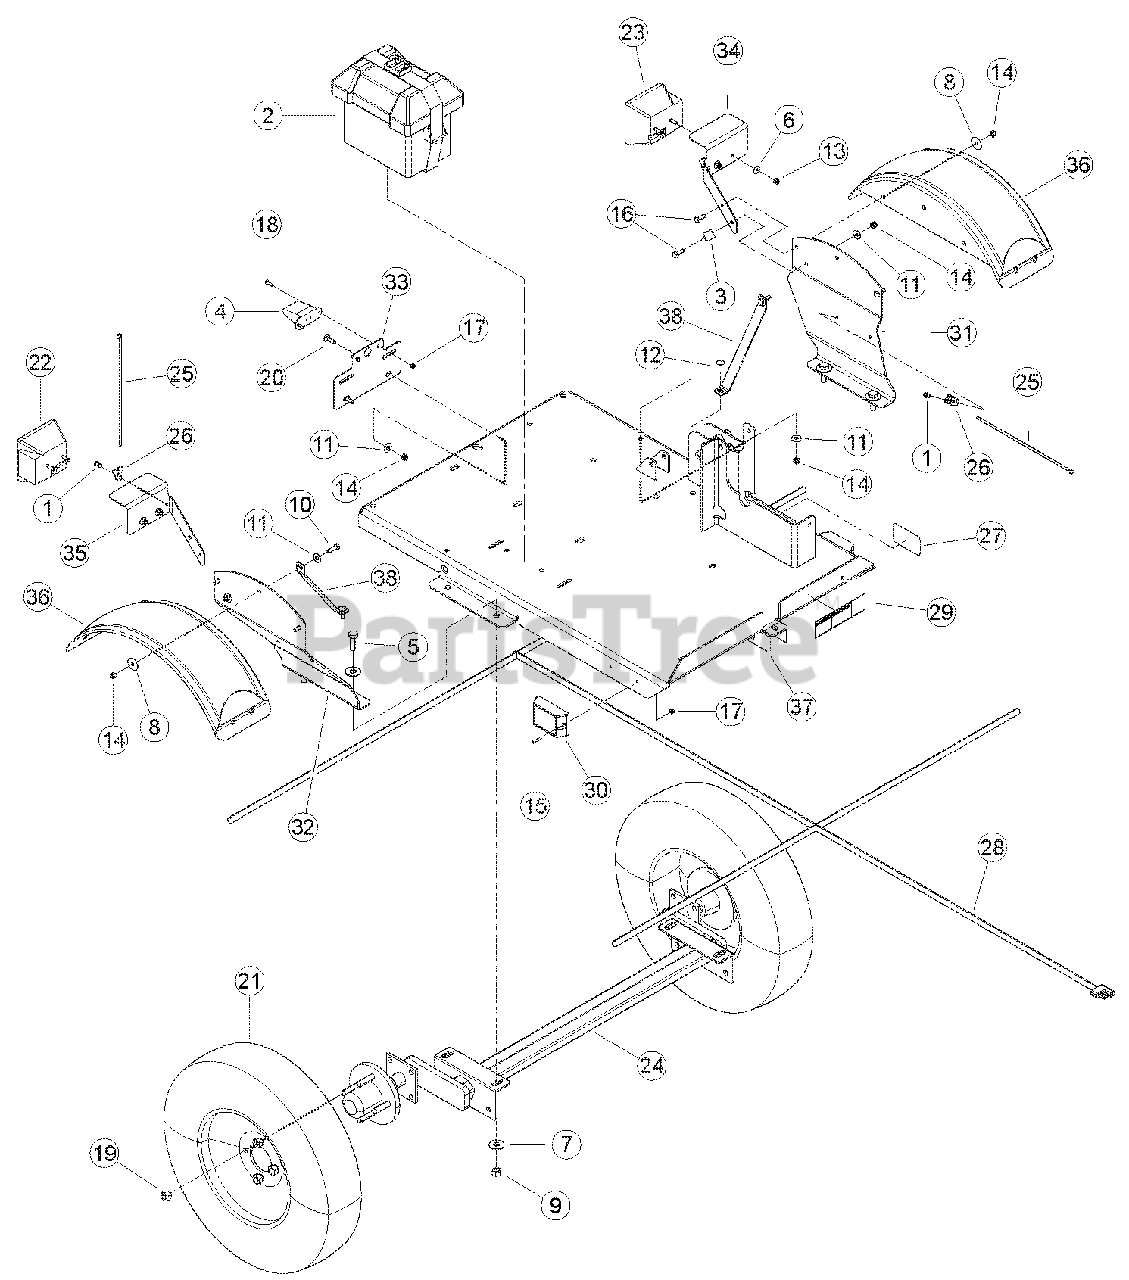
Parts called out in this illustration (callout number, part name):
1	RIVET, 1/4 X 3/4 ST POP
2	BOX, SMALL BATTERY
3	CLAMP, 9/16" COATED
4	LIGHT, LICENSE PLATE
5	REFLECTOR, WIDE ANGLE AMBER
6	BOLT, 1/2 X 1-1/2 HEX HD GR5 ZP
7	WASHER, 1/4 FLAT ZP
8	WASHER, 1/2 FLAT ZP
9	WASHER, 5/16 FENDER ZP
10	NUT, 1/2 CENTERLOCK GRB ZP
11	BOLT, 5/16 X 1 HEX HD GR5 NC ZP
12	WASHER, 5/16 FLAT ZP
13	BOLT, 5/16 X 1 CRG GR5 ZP
14	NUT, 1/4 NE NYLOCK ZP
15	NUT, 5/16 NE NYLOCK ZP
16	BOLT, 5/16 X 7/8 HHCS NC GR5 ZP
17	NUT, 10/24 NYLOCK TYPE NM, ZP
18	MACHINE SCREW, #10-24 X 3/4 PAN HD PH ZP
19	NUT, 1/2-20 WHEEL
20	BOLT, 5/16 X 1 CRG GR5 UNPLATED
21	ASSEMBLY, 5.30-12 TIRE + SPOKE RIM
22	LIGHT, LH TAIL
23	LIGHT, RH TAIL
24	AXLE, 1000LB TORSION
25	STRAP, 11 IN BLACK TIE
26	CLAMP, CABLE MOUNT
27	HARNESS, CHIPPER TRAILER
28	DECAL, 5.30-12 LOAD RATING
29	BRACKET, LH FENDER
30	BRACKET, RH FENDER
31	PLATE, LICENSE
32	BRACKET, LIGHT LH
33	BRACKET, LIGHT RH
34	FENDER, BLACK PLASTIC DRILLED
35	WELDMENT, CHIPPER TRAILER
36	BRACKET, FENDER
